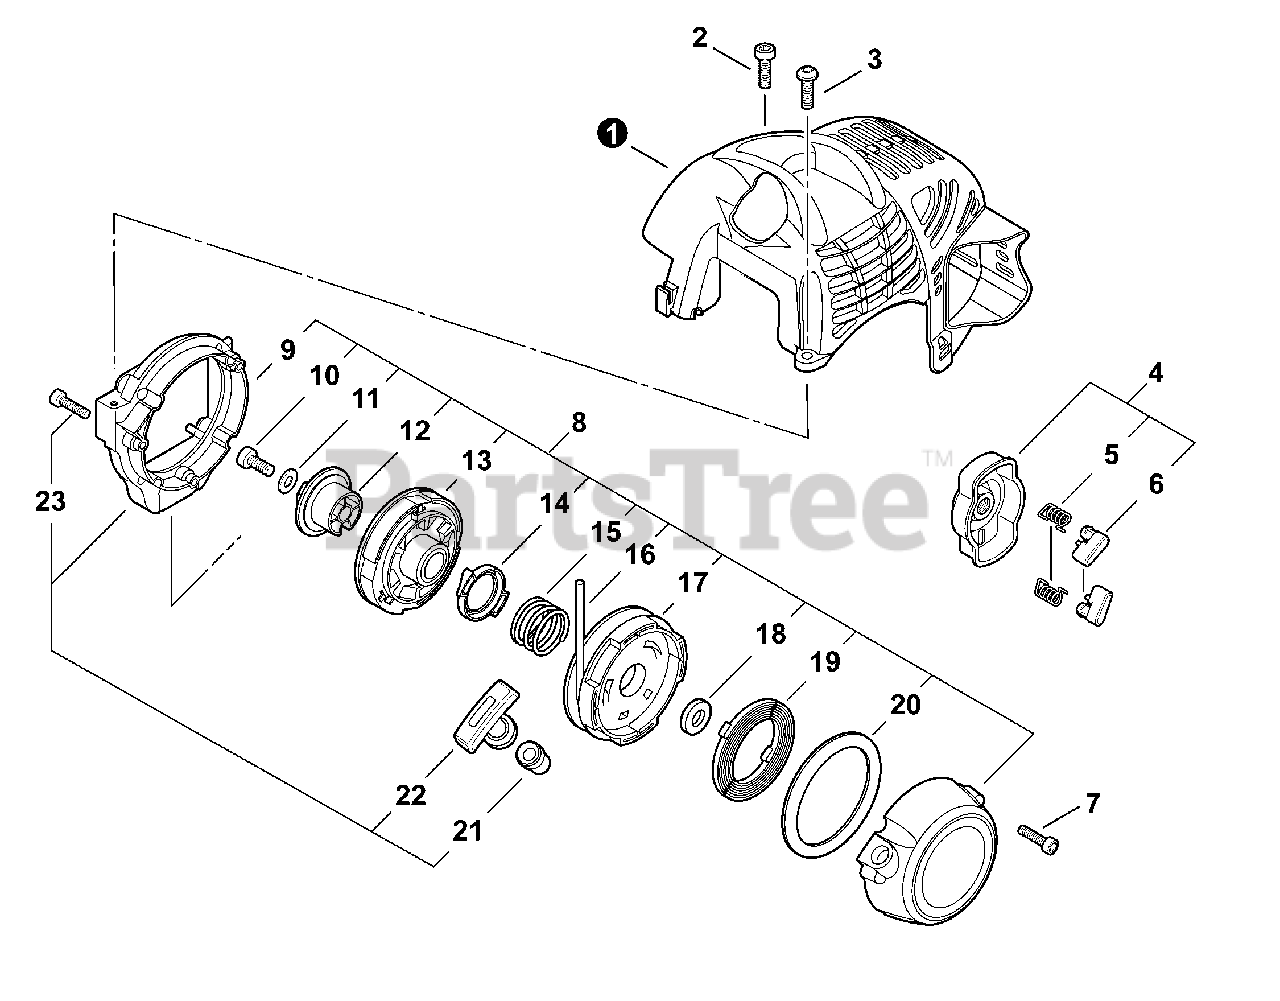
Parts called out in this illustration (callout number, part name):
1	COVER, ENGINE
2	BOLT, TORX 5×16
3	BOLT, TORX 5×16
4	PAWL ASSY, STARTER
5	SPRING, RETURN
6	PAWL, STARTER - BLACK
7	BOLT, TORX 4×16
8	STARTER ASSY, RECOIL
9	BRACKET, STARTER
10	BOLT, TORX 5×12
11	WASHER 5.5×12×0.8
13	CLUTCH ASSY
16	ROPE, STARTER 3×900
18	COLLAR 8
19	SPRING, RECOIL
20	PLATE, STARTER
21	GUIDE, ROPE
22	GRIP, STARTER
23	BOLT, TORX 4×16
